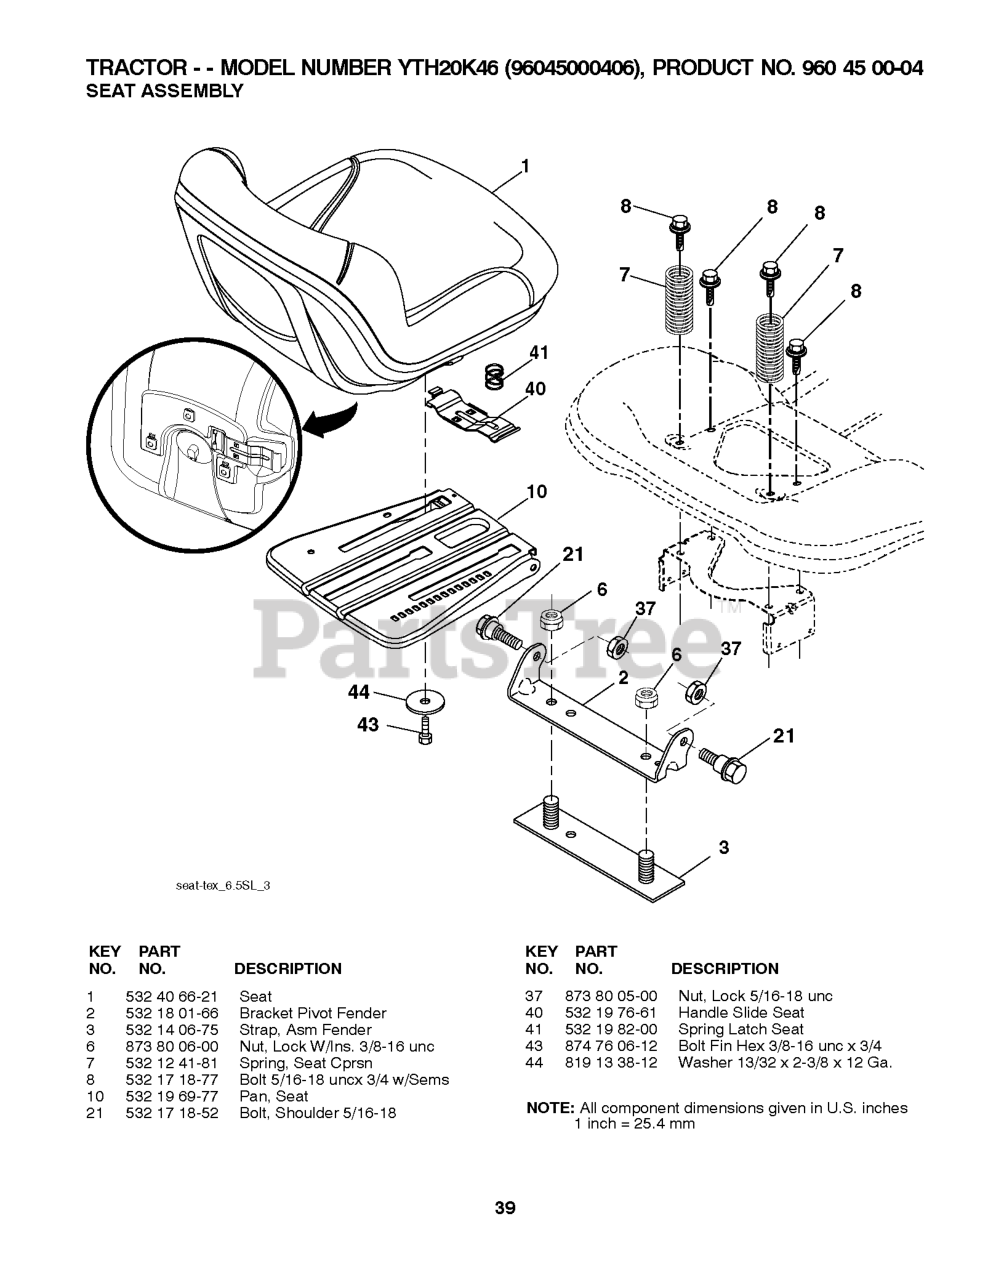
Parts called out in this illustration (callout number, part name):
1	SEAT - GREY
2	BRKT.PIVOT.FENDER
3	STRAP
6	NUT
7	SPRING COMPRESSION
8	BOLT.5/16-18UNCX3/4 W/SEMS.BLK
10	PAN.ASM.SEAT.3PT
21	BOLT.SHOULDER.5/16-18
37	NUT.71038.31-18.HEX.NYLOCK
40	HANDLE.SLIDE.SEAT.TEX.BLACK
41	SPRING.LATCH.SEAT.TEX
44	WASHER 13/32 X 2-3/8 X 12GA
